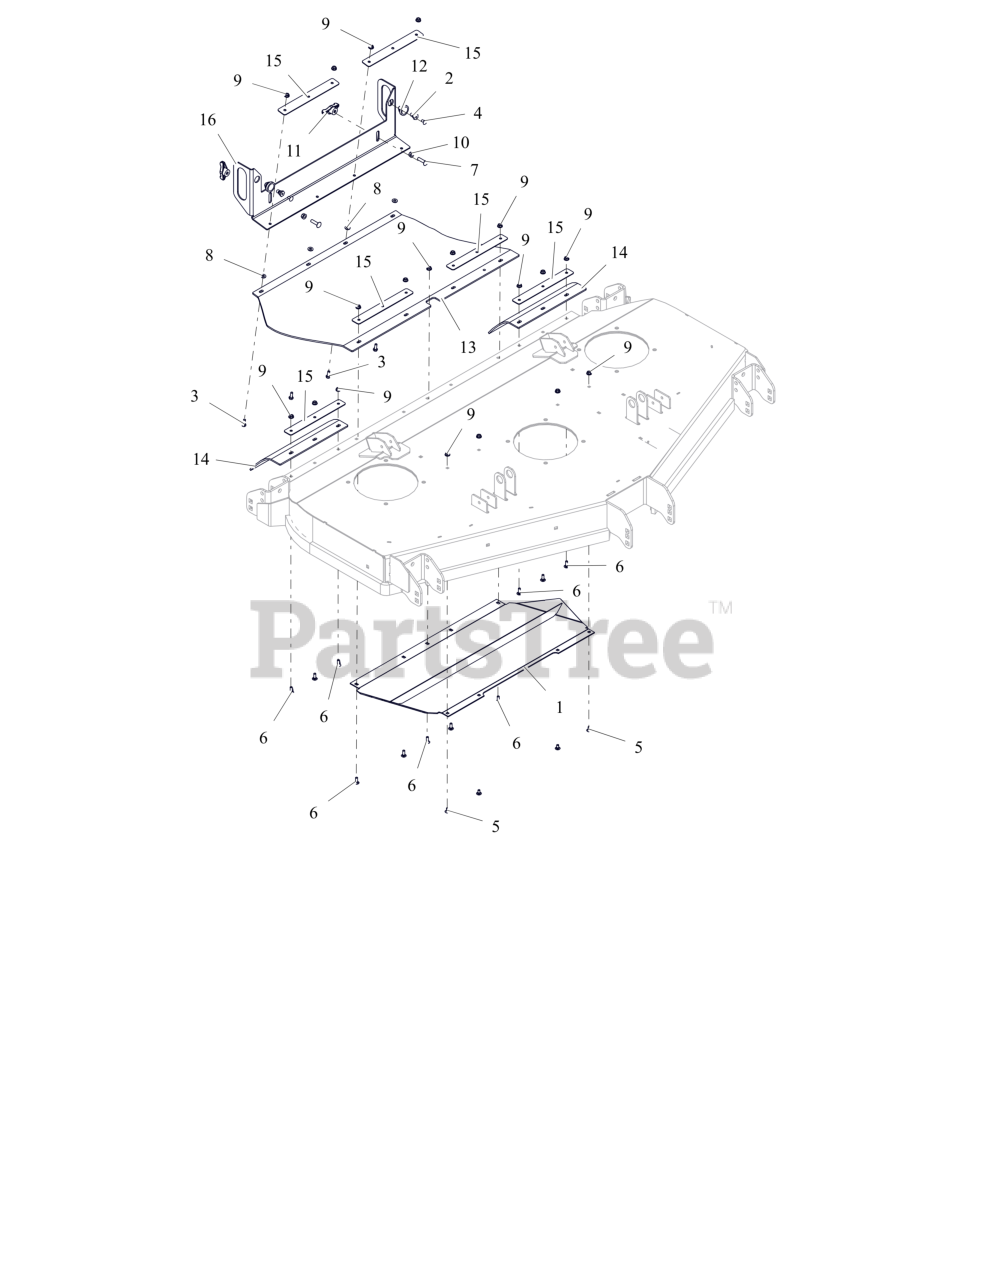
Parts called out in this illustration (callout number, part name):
1	WLDMT, DEFLECTOR BAFFLE (RED)
2	STUD, BALL FEMALE .250-20 THREAD
3	BLT, HEX .25-20X.75 G5 ZCC
4	BLT, RHSSN.25-20X.500 G5 ZCC
5	BLT, RHSN .25-20X.500 G5 ZCC
6	BLT, RHSN .25-20X.750 G5 ZCC
7	BTL,RHSSN .313-18 X 1.25 G5 ZCC
8	WSHR,FLT .281X.625X.065 ZCC
9	NUT-LK-CTR-FLG .25-20 ZC120
10	NUT,LK-CTR-FLG .31-18 GF ZCC
11	KNOB,WING .31-18 UNC NYL/TALC
12	COUPLING, RUBBER PUSH-IN
13	CHUTE, REAR DISCHARGE EV
14	CHUTE, TIRE REAR DISCHARGE
15	PLATE, CHUTE MTG (BLACK)
16	HANDLE, CHUTE MOUNTING (RED)
